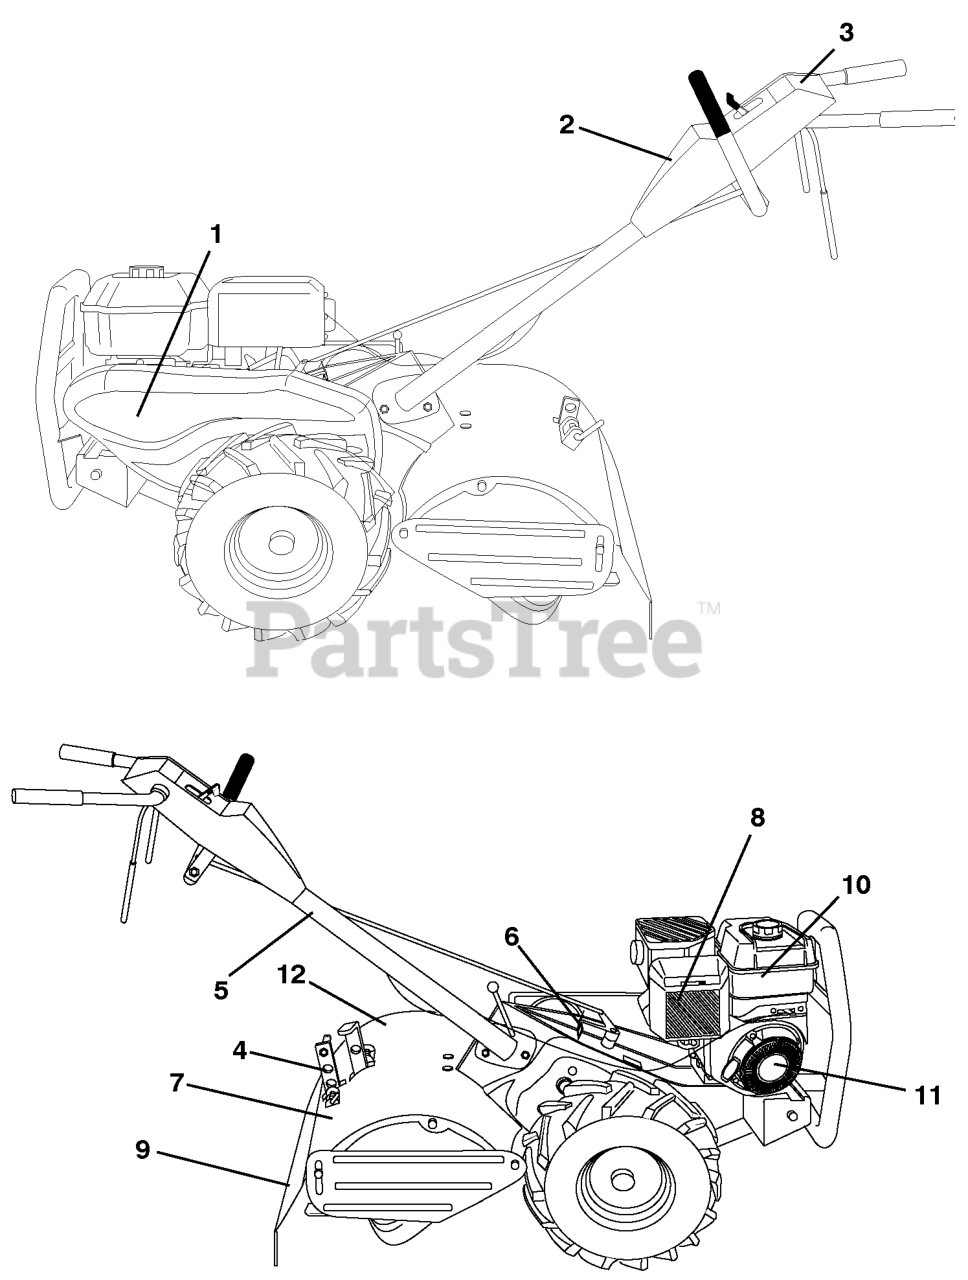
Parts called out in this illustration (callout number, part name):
1	DECAL.HOOD.LOGO.ORANGE.HUSQVAR
2	DECAL.CNSL.DRT900/HUSQVARNA
3	DECAL.TILLER.CNSL.INS.
4	DECAL.SHIELD.TN.DRT17.HUSQ.008
5	DECAL TI (2 2)
6	DECAL.SHIFT.INDICATOR.DRT
7	DECAL.REVERSE.HUSQ
8	DECAL, ENGINE B&S
9	DECAL.DRT.WARN.ENG/F
10	DECAL.B&S.900.TANK.REF.276991
11	DECAL, REWIND STARTER, B&S
12	DECAL.FORWARD.HUSQ
